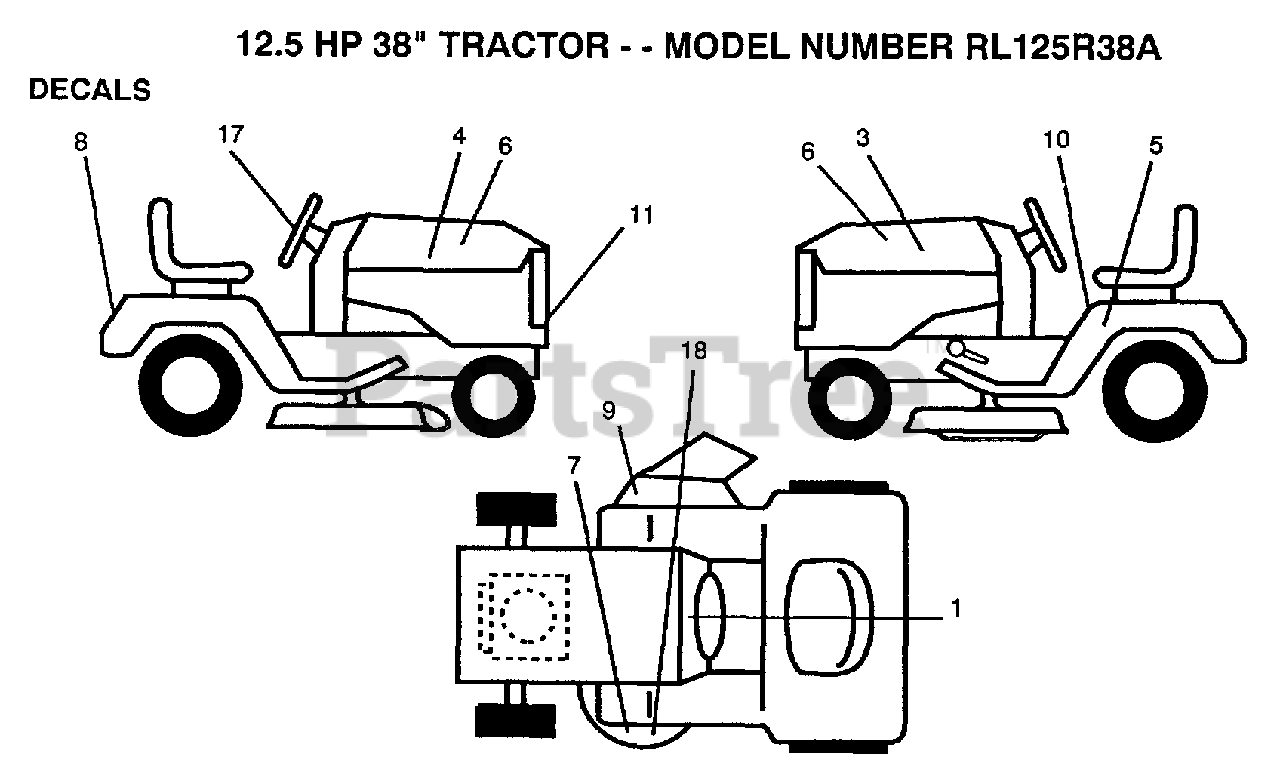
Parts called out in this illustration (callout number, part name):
5	IND HGT DECK DECA
7	DECAL YT
8	FENDER DECAL
9	DECAL WARNING
10	DECAL CAUTION
11	GRILL DECAL
17	"DECAL,STR WHL"
